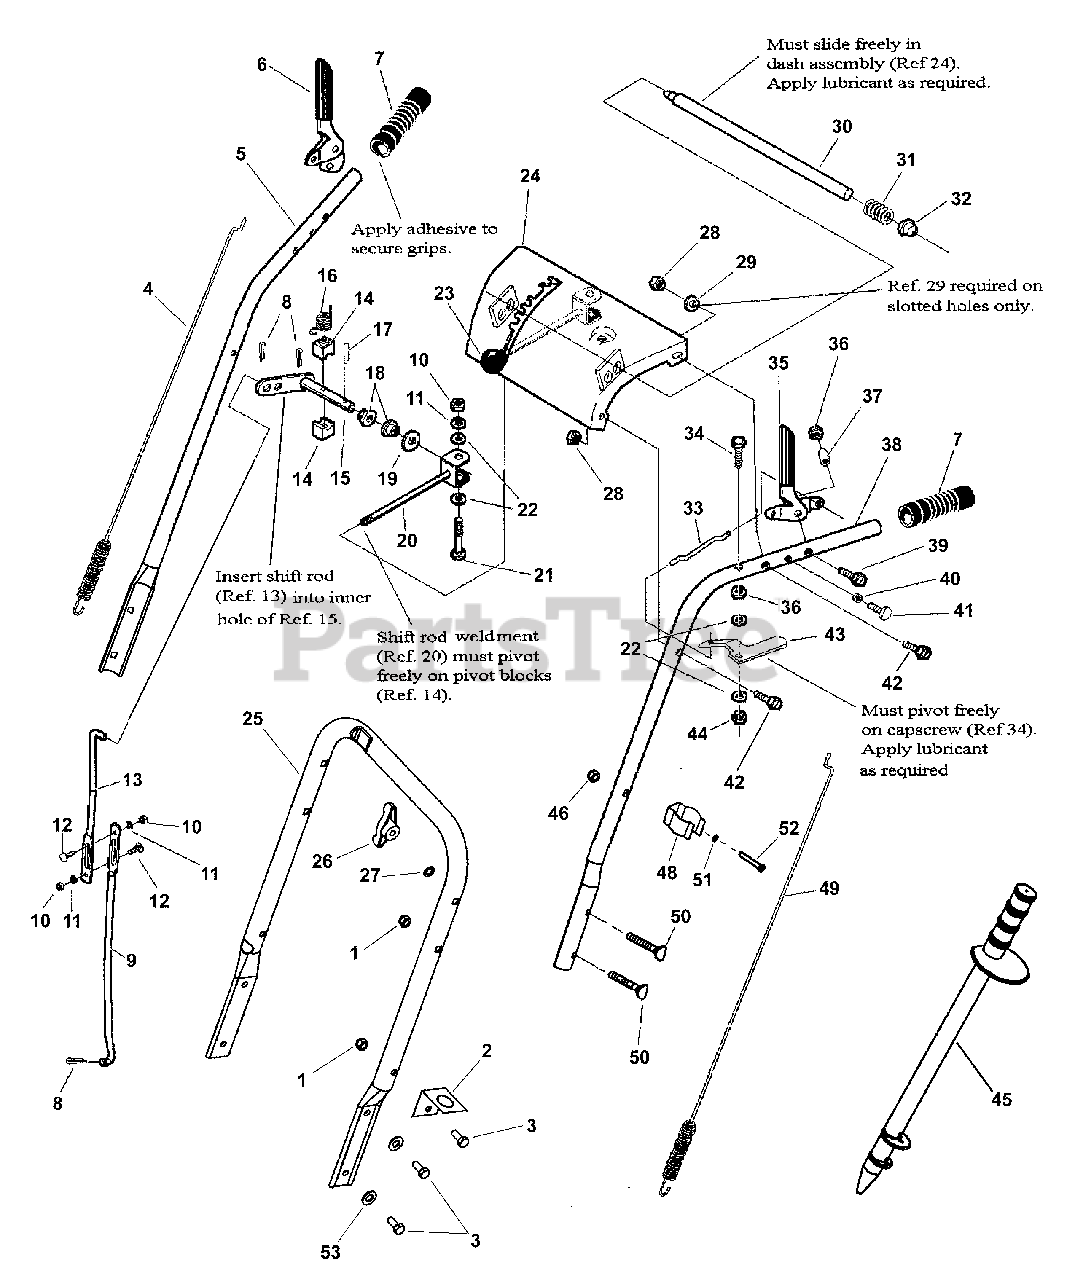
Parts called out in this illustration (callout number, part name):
1	NUT, 5/16-18 Hex Nyloc
2	BRACKET, Snow Stick- Lower
3	SCREW, 5/16-18 x 3/4" Hex Head Cap
4	CLUTCH CABLE, Auger Drive- RH
5	HANDLE, Upper, Right Hand
6	GRIP, Clutch, RH
7	GRIP, Foam, Black
8	HAIR PIN
9	ROD, Shift, Lower
10	NUT, 1/4-20 2B Hex
11	LOCKWASHER, 1/4" Spring
12	BOLT, 1/4-20 x 2" Short Square Neck Carriage, GR 5
13	ROD, Upper, Shift
14	BLOCK, Pivot
15	SHIFT ROD PIVOT ASSEMBLY
16	SPRING, Compression
17	COTTER PIN, .125 x 1.00
18	BUSHING, .500 ID x .750 OD x .25
19	WASHER, 1/2" Flat (.531 ID x 1.250 OD x .08 Thick)
20	SHIFT ROD ASSEMBLY
21	SCREW, 1/4-20 x 2-1/4" Hex Flange Lock
22	WASHER, .250 (.27 ID x .62 OD)
23	KNOB, Tapered - 3/8-16 Internal Thread- Red
24	DASH ASSEMBLY
25	HANDLE, Lower
26	WING KNOB, 5/16-18
27	WASHER, 5/16" Internal Tooth Lock
28	NUT, 5/16-18 Hex Flange Nyloc
29	WASHER, .312 (.34 ID x .75 OD)
30	ASSEMBLY, Rod w/Pin (Includes Ref. Nos. 31. 47, 54, 55 & 56)
31	SPRING, Compression
32	PUSH NUT
33	ROD, Hold Down
34	SCREW, 1/4-20 x 2" Hex Head Cap, GR 5
35	GRIP, Clutch, LH
36	NUT, 1/4-20 Hex Centerlock
37	SPACER, Handle
38	HANDLE, Upper, Left Hand
39	SCREW, 1/4-20 x 1-1/2" Hex Head Cap
40	SPACER, .268 ID x .394 x .165
41	SCREW, 1/4-20 x 3/4" Pan Head Torx Self-Tap
42	SCREW, 5/16-18 x 1-1/2" Hex Head Cap, GR 5
43	LEVER, Pivot
44	NUT, 1/4-20 Hex Nyloc
45	TOOL, Clean-Out
46	NUT, #10-24 Hex Center Lock
48	HOLDER, Clean-Out Tool, Upper
49	CLUTCH CABLE, Ground Drive- LH
50	BOLT, 5/16-18 x 2" Curved Head Square Neck GR 2
51	WASHER, #10 Internal Tooth Lock
52	SCREW, #10-24 x 2" Hex Washer Head Machine, GR5
